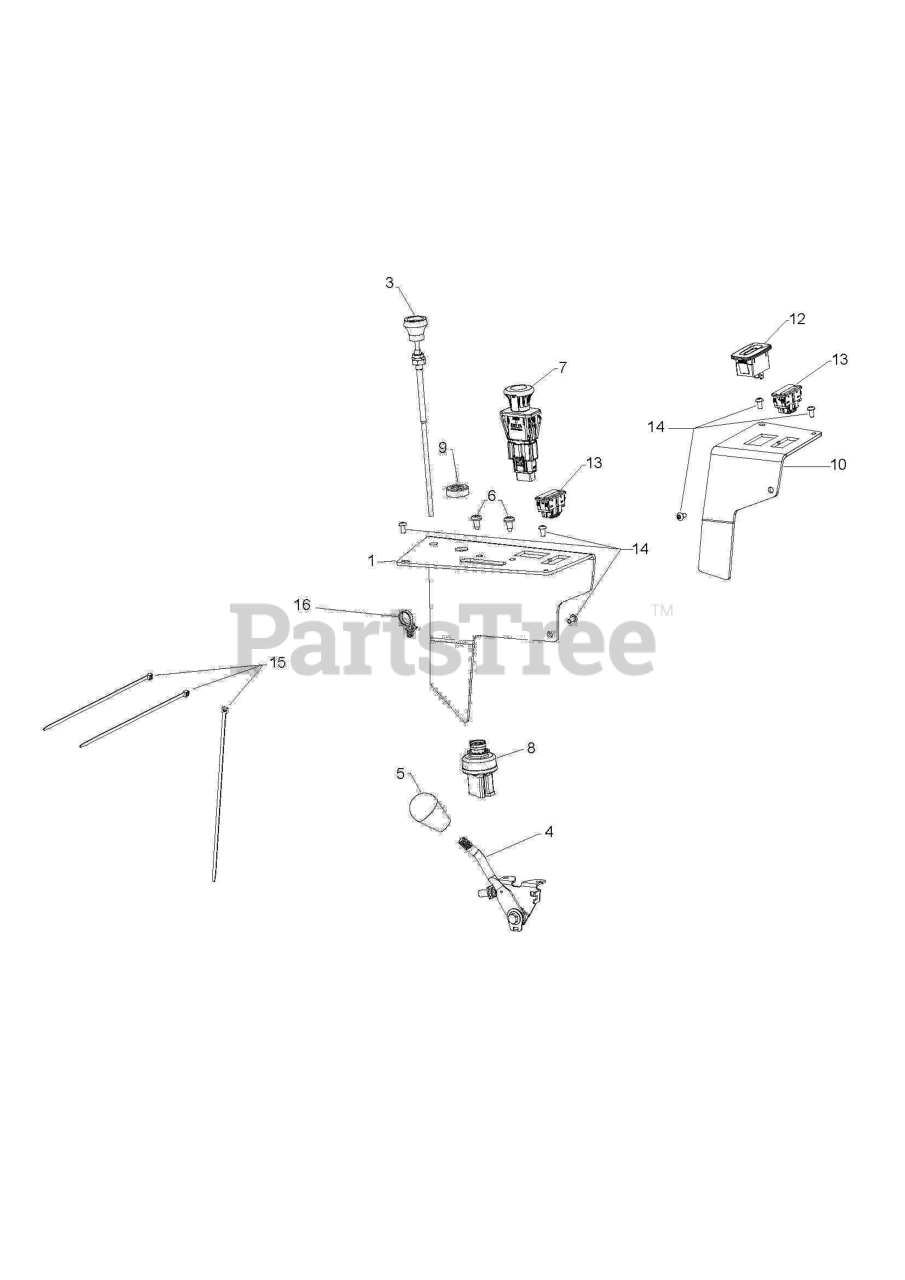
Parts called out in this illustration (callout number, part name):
1	Control Panels
1	DECALZTR.CONTROLPANEL.PZ500.RH
3	Cables
5	KNOB - SHIFT
6	SCREW T-30 1/4-20 X
7	SWITCH.PTO.10AMP.SEALED.6P.SPS
8	SWITCH, IGNITION, INDAK
9	CAP IGNITION NUT
10	PANEL.LH.CONTROL.PNT.X498
12	GUAGE.SRVCMNDR.HRMTR.
13	FUEL.GAUGE.LED.LEVEL.Z500
14	SCR #10-24 X 3/8 SKT HD BLK OX
15	TIE, PLASTIC
16	TIE WRAP, 8-3/8", W/CLIP
